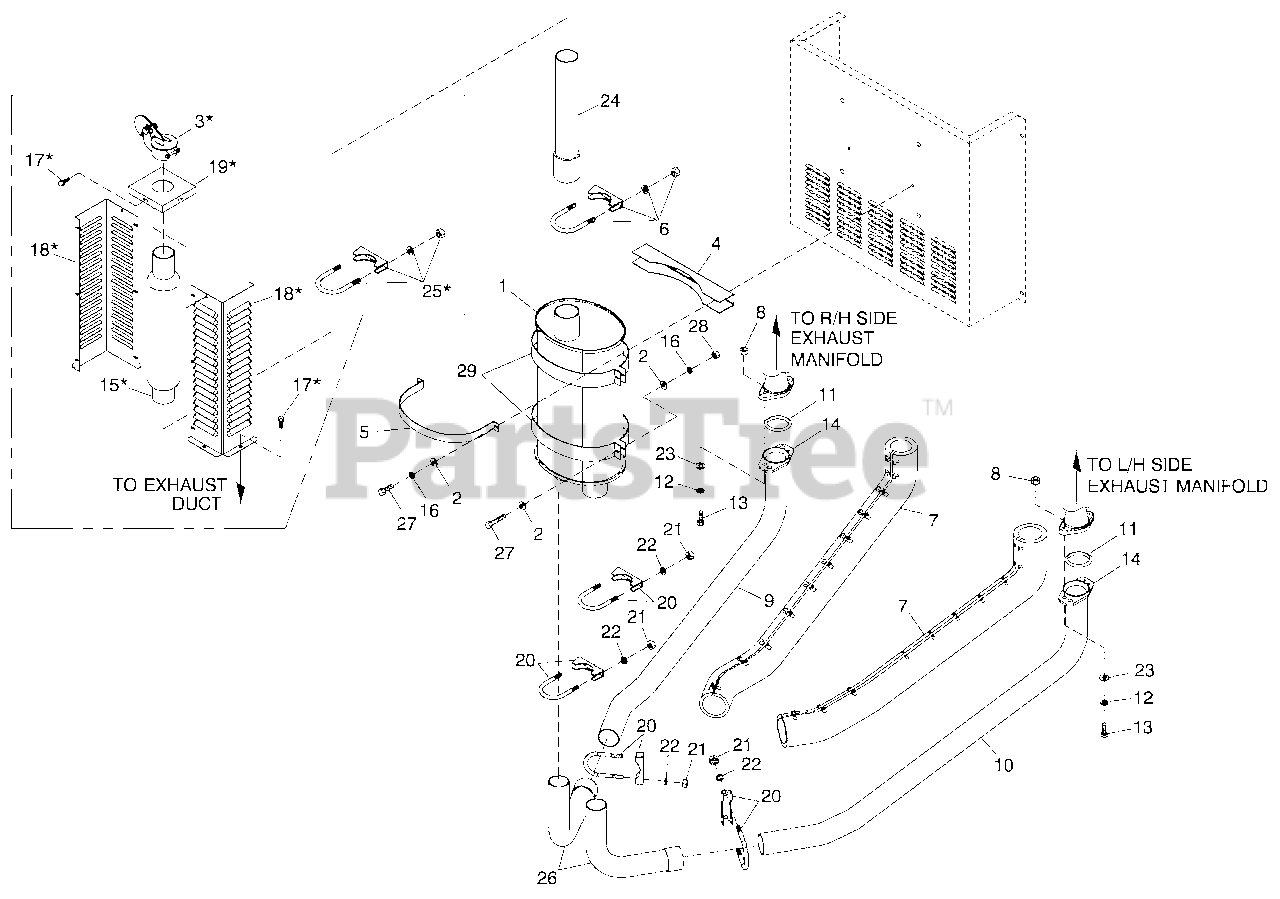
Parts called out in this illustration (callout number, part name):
1	MFLR 7" X 9" (2) 2" IN/2.5" OUT
2	WASHER FLAT 1/4-M6 ZINC
3	RAIN CAP ALUM FOR 2 1/2" PIPE
4	MUFFLER BRACKET STIFFENER
5	MUFFLER STRAP
6	BOLT U 3/8-16X2.62
7	EXHAUST BLANKET 850MM (C4)
8	NUT HEX 3/8-16 SSTL
9	PIPE EXH MANIFOLD RH
10	PIPE EXH MANIFOLD LH
11	GASKET EXHAUST RING
12	WASHER LOCK 3/8 SS
13	SCREW HHC 3/8-16 X 2 SS FTH
14	EXHAUST FLANGE 2" PIPE
15	GLASS PACK 23.5" LG 2.5" IN/OUT
16	WASHER LOCK M6-1/4
17	SCREW THF M6-1 X 16 N WA Z/JS
18	HEAT SHIELD EXHAUST STACK
19	CAP HEAT SHIELD EXHAUST STACK
20	BOLT U 5/16-18X2.25
21	NUT HEX 5/16-24 STEEL
22	WASHER LOCK M8-5/16
23	WASHER FLAT 3/8 SS
24	EXHAUST OUTLET PIPE CPL
25	BOLT U 3/8-16X2.62
26	PIPE EXHAUST ELBOW C4
27	SCREW HHC M6-1.0 X 35 G8.8 BLK
28	NUT HEX M6 X 1.0 G8 YEL CHR
29	MUFFLER STRAP UPPER/LOWER
